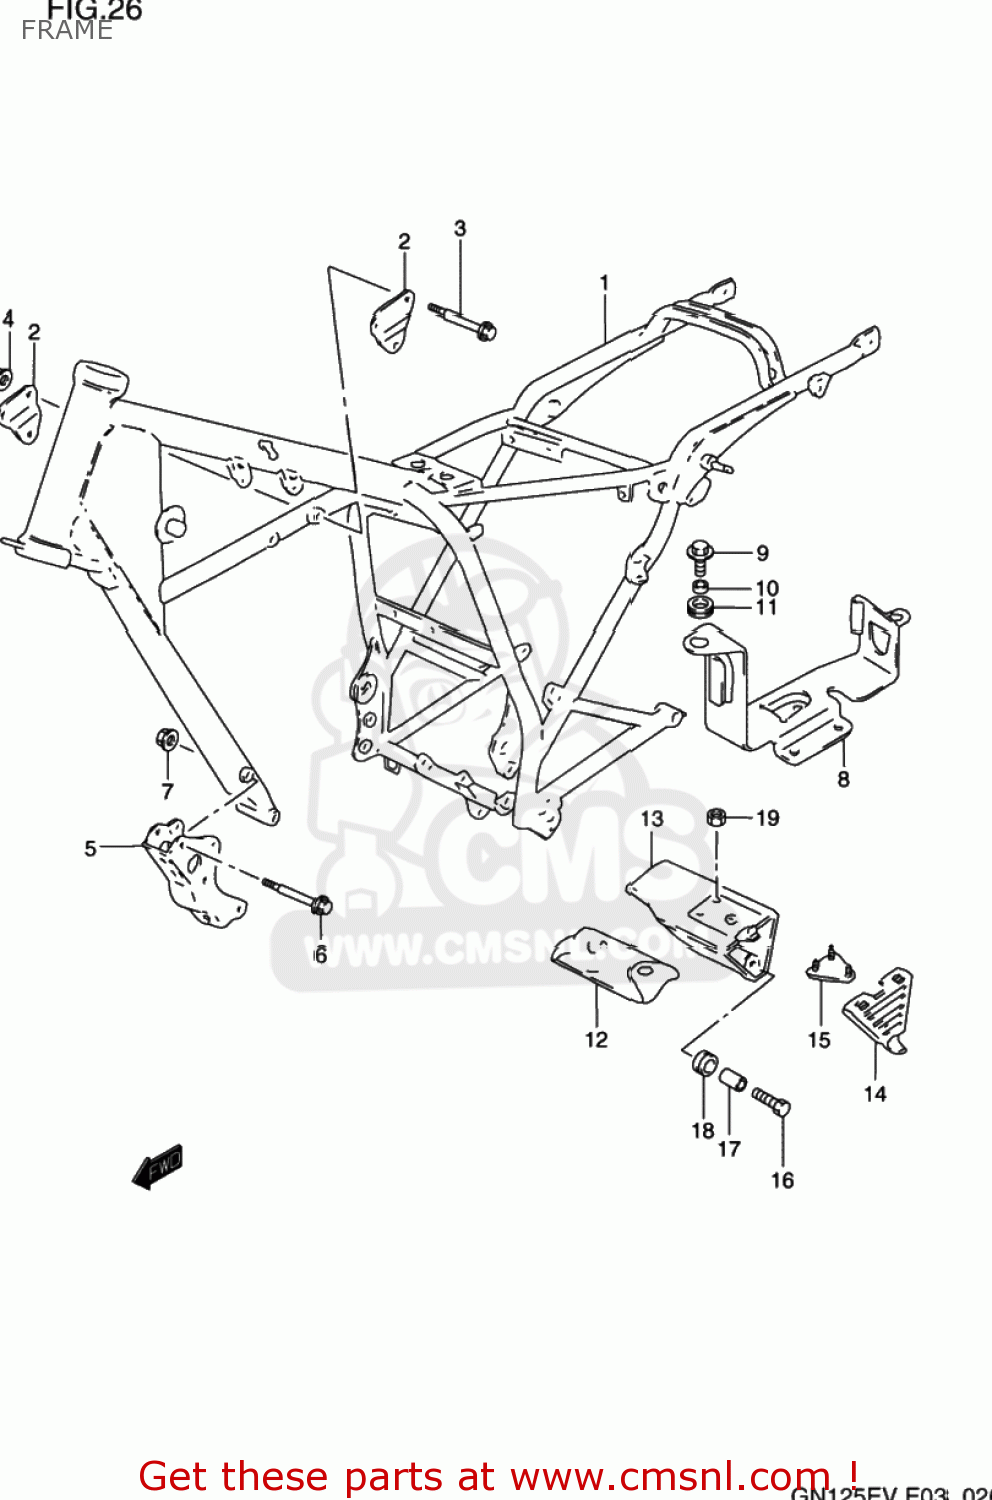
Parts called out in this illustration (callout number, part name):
1	FRAME COMP
2	PLATE,ENGINE MOUNTING
3	BOLT(8X50)
4	NUT
5	BRACKET,ENGINE MOUNTING LWR
6	BOLT
7	NUT
8	HOLDER,BATTERY
9	BOLT(6X16)
10	SPACER(6.1X9X7.5)
11	CUSHION
12	TOOL ASSY
13	BOX,TOOL
14	CAP,TOOL BOX
15	PLATE,TOOL HOLDER
16	BOLT(6X16)
17	SPACER(6.1X9X7.5)
18	CUSHION
19	NUT
